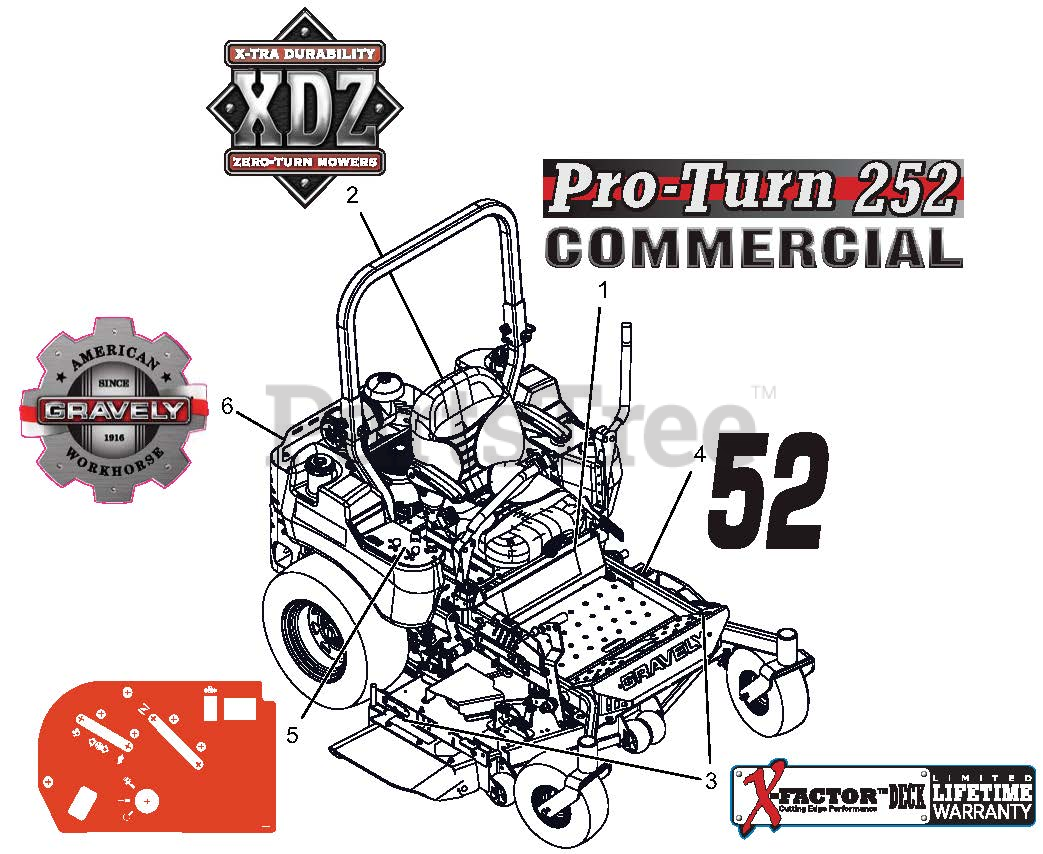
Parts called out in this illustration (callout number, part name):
1	DECAL, PROTURN 252
2	DECAL, XDZ
3	DECAL, X-FACTOR DECK
4	DECAL, 52"
5	DECAL, CONTROL PANEL NON-EFI
6	DECAL, GRAVELY HERITAGE-LARGE
